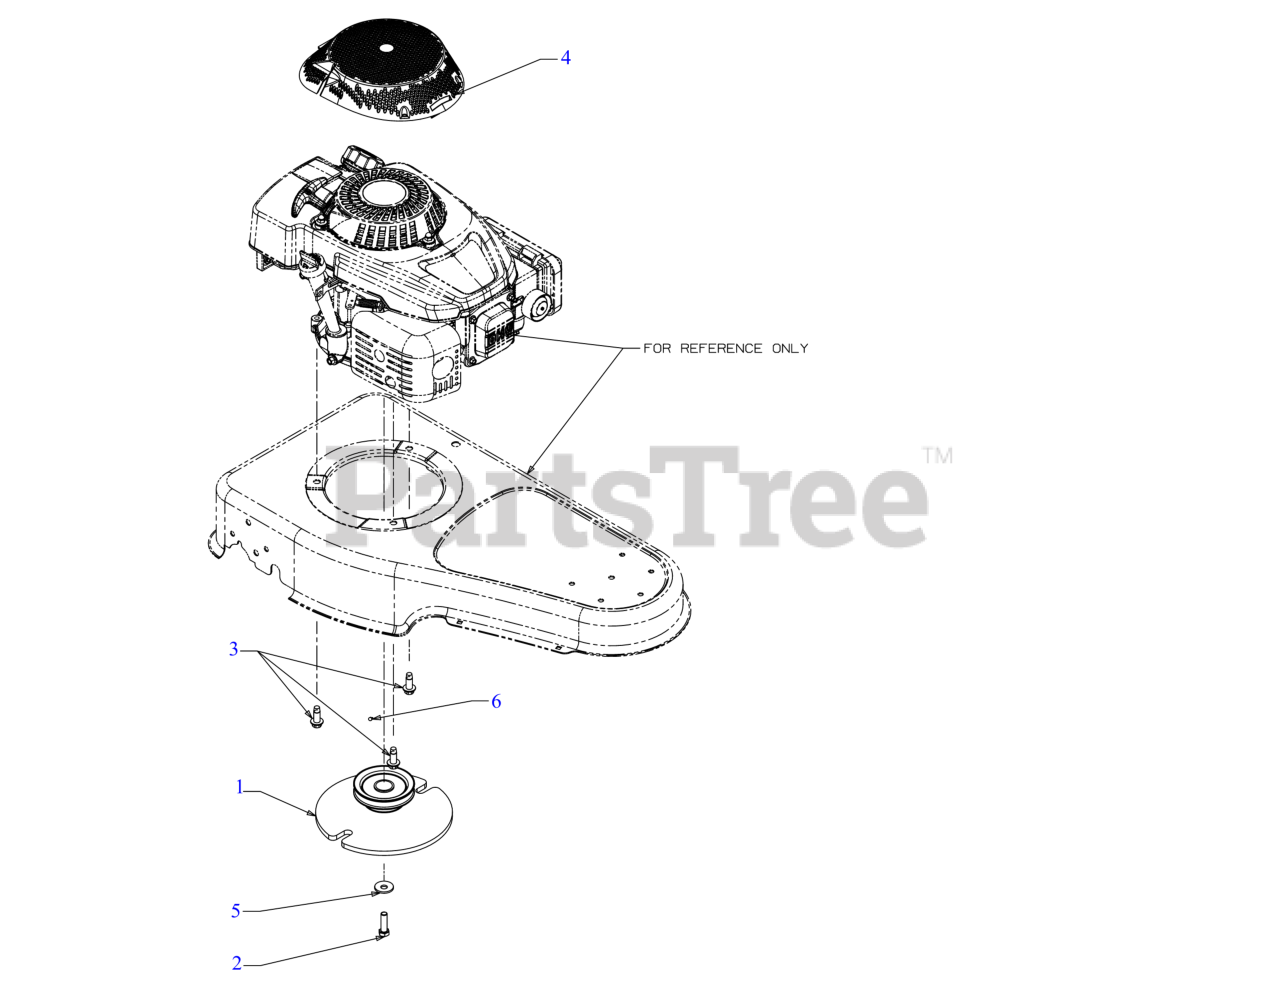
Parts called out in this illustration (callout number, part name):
1	FLYWHEEL PULLEY
2	SCREW 3/8-24X1.25
3	SCREW 3/8-16 x 1
4	SHROUD DEBRIS COVER
5	BELL WASHER
